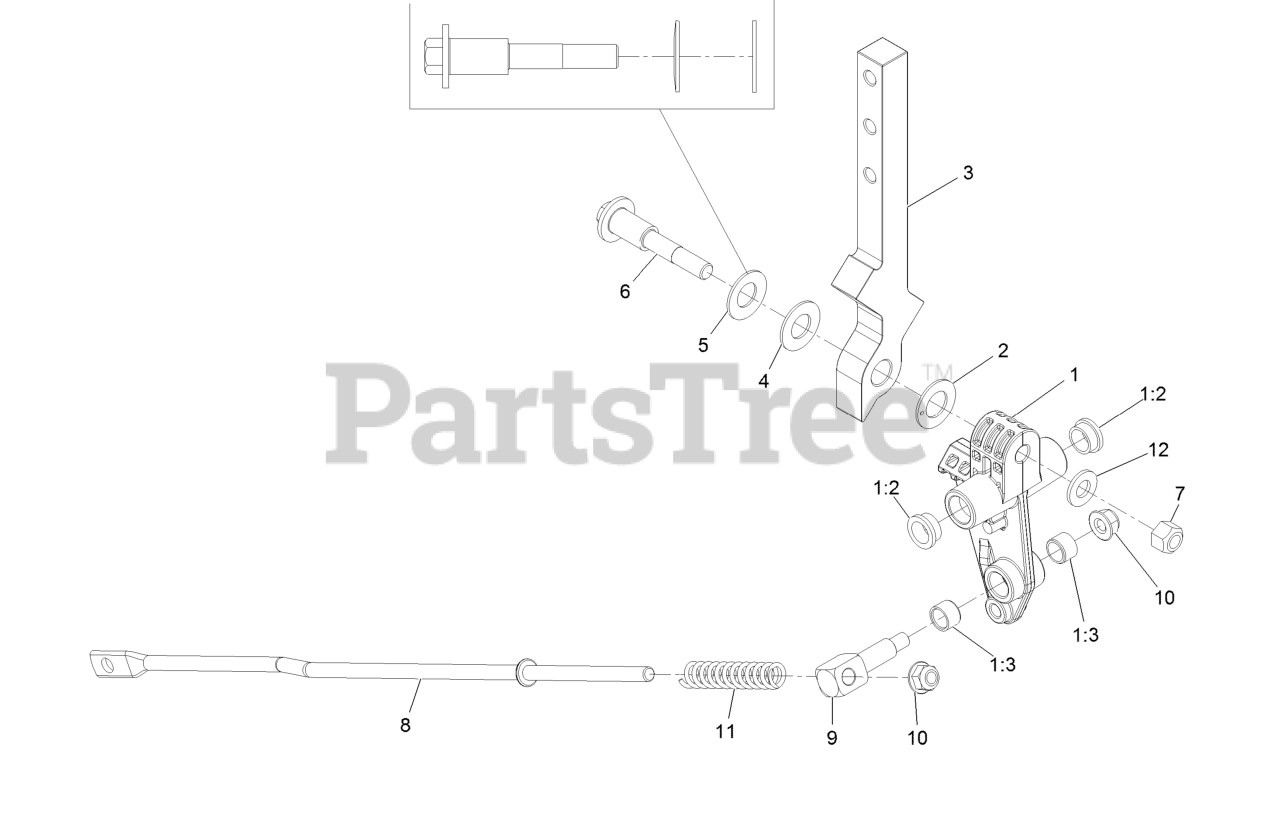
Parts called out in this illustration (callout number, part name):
1	Control Arm ASM
1:2	Bushing
1:3	Bushing-Sleeve
2	Washer-Friction
3	Arm-Control
5	Washer-Belleville
6	Bolt-Pivot
7	Nut-Hex 3/8-16 Lock
8	Link-Control
10	Nut-Nyloc 5/16-18 Flg
11	Spring-Return, Neutral
12	Washer-3/8 SAE
